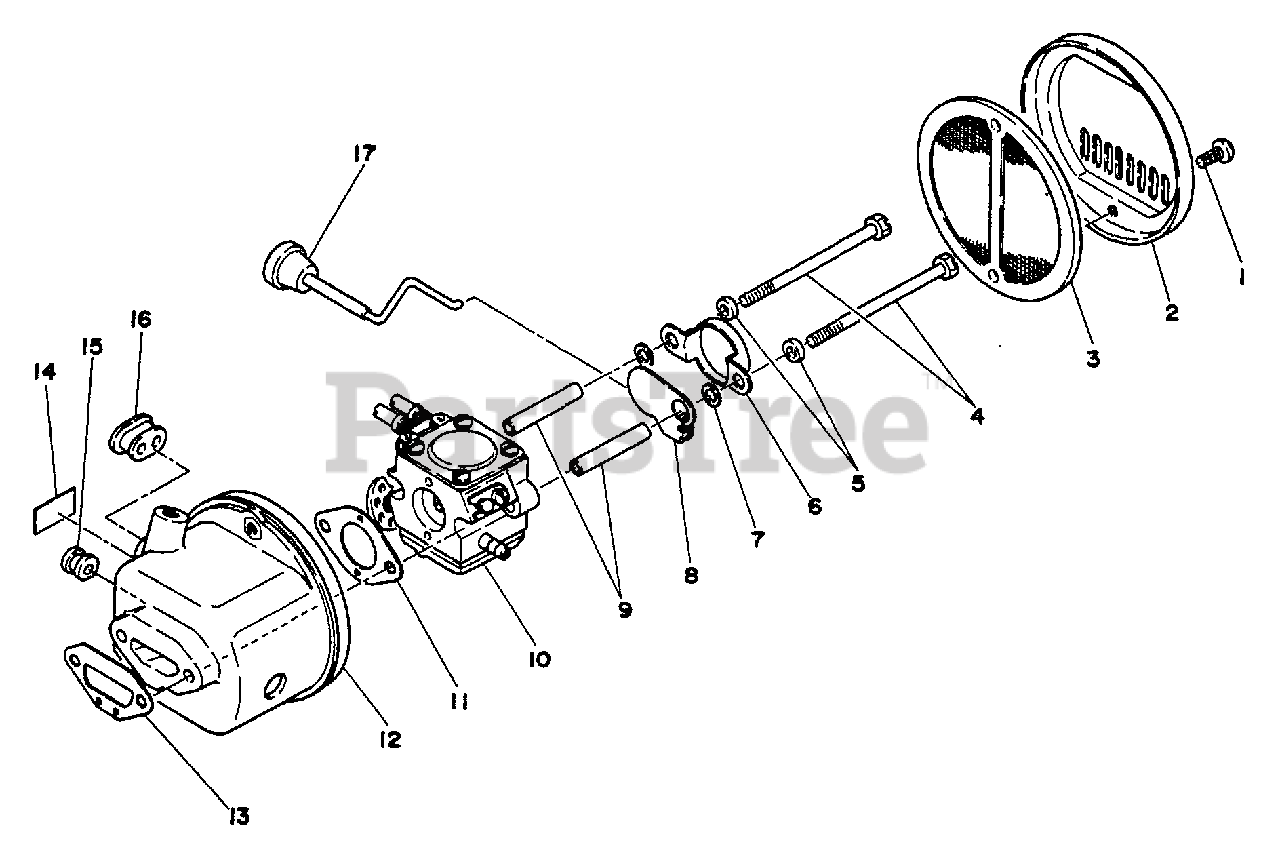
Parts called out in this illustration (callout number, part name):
1	SCREW 4×10
2	COVER, AIR FILTER
3	FILTER, AIR
7	WASHER 5.5×8×0.8
8	SHUTTER, CHOKE
9	SPACER
10	CARBURETOR - WA-21
11	GASKET, INTAKE
12	CASE, CARBURETOR
13	GASKET, INTAKE
14	LABEL - FUEL ADJUST
15	GROMMET, CHOKE
17	ROD, CHOKE
